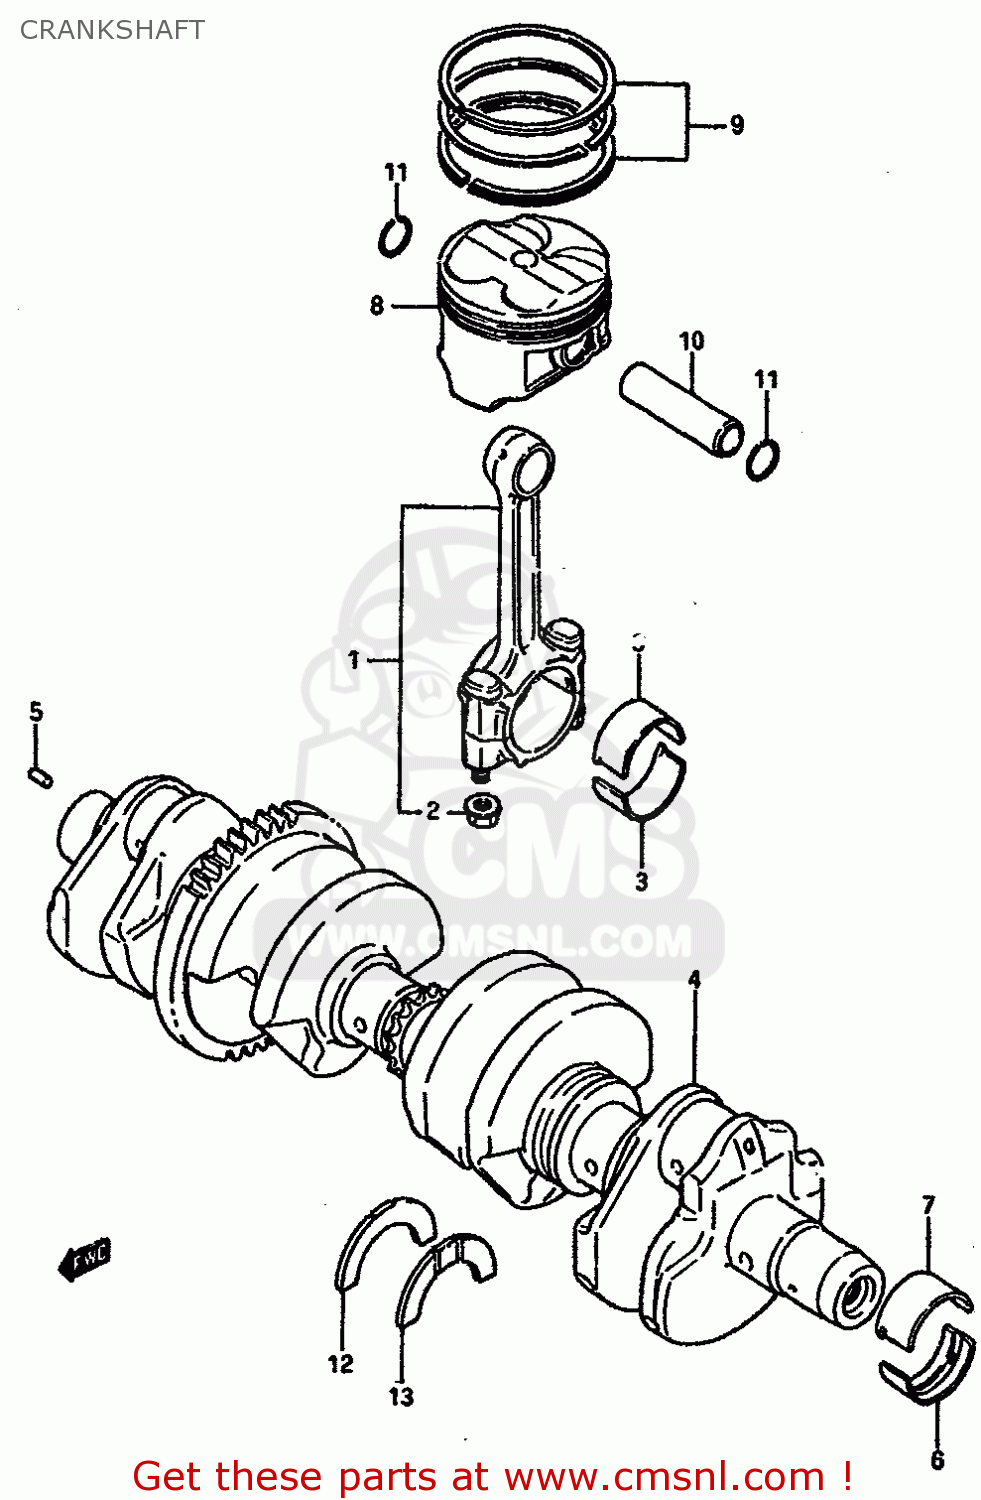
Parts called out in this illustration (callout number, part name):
1	ROD ASSY,CONNECTING
2	NUT
3	BEARING,CRANK PIN
4	CRANKSHAFT
5	PIN
6	BEARING,CRANKSHAFT LWR
7	BEARING,CRANKSHAFT UPR
8	PISTON
9	RING SET,PISTON
10	PIN,PISTON
11	CIRCLIP
12	PLATE,CRANK THRUST
13	PLATE,CRANK THRUST
